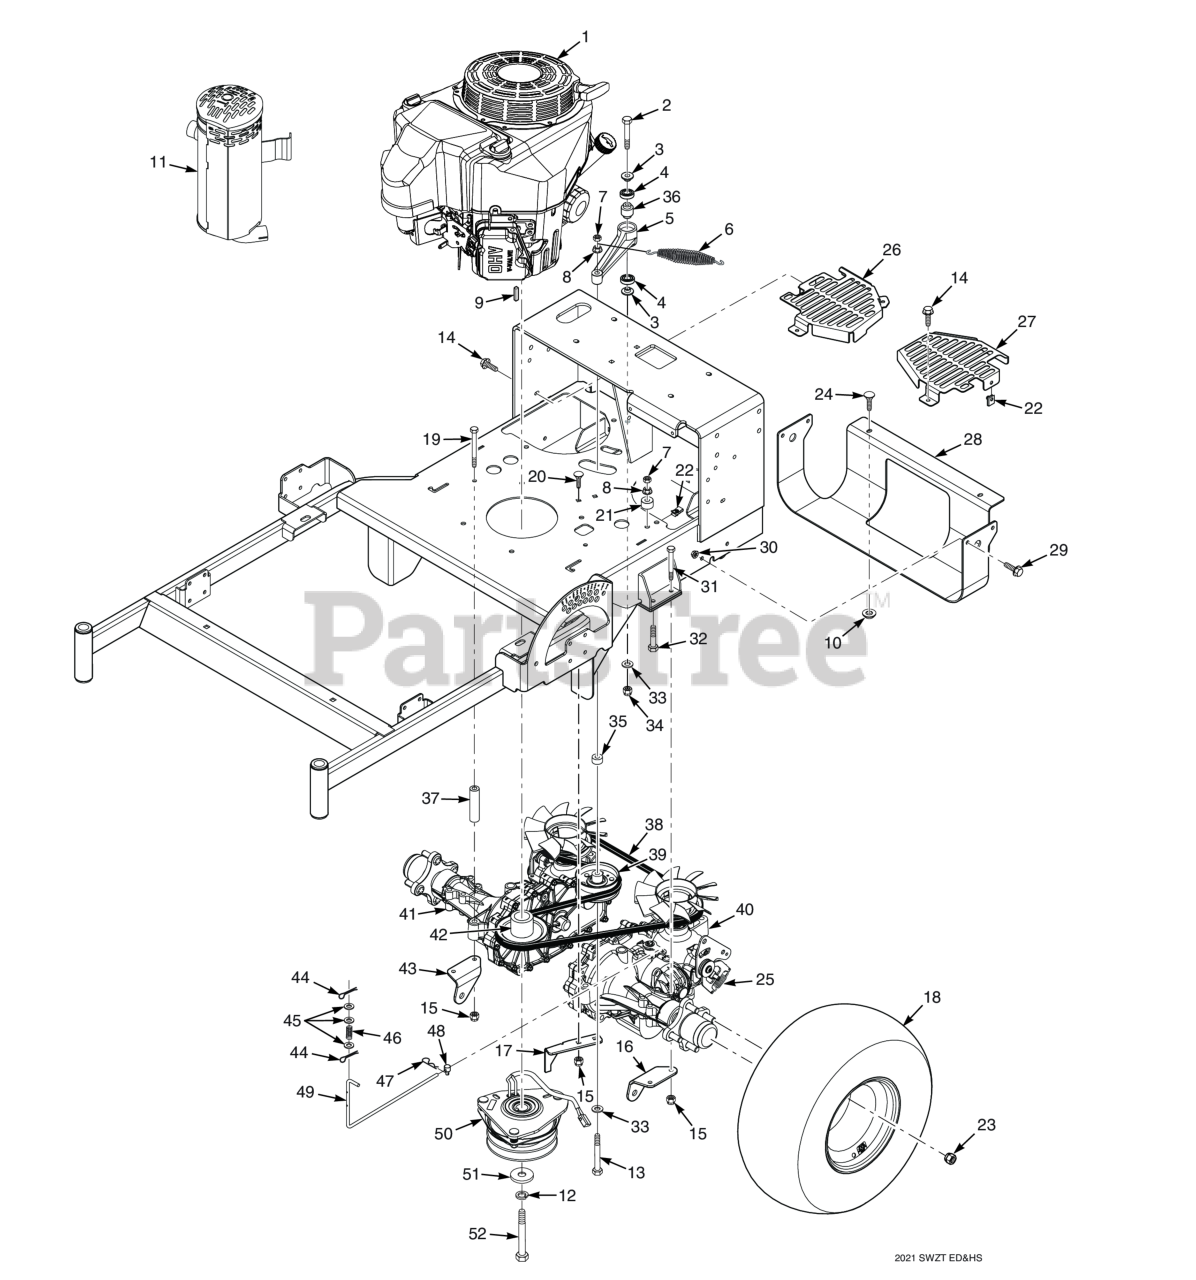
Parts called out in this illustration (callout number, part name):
1	Engine, Kawasaki 14FS (FS481V)
2	Bolt, Hex Head 3/8-16 x 3" - 52"
3	Spacer, Controls
4	BEARINGS, BALL, NEUTRAL RETURN
5	Trans. Idler Arm Assy. (Includes 24, 79)
6	Spring, Transmission Idler
7	Bolt, Hex Head 3/8-16 x 1" Ser. Flg.
8	NUT, 3/8-16 SERRATED FLANGE HEX HEAD
9	KEY, 1/4 X 1/4 X 2-1/2"
10	Nut, Push-On 5/16-18
11	Muffler, Kawasaki (FS651) - SWZT61
12	Lockwasher, 7/16� Spring
13	Capscrew, Hex Head 3/8-16 x 3-3/4"
14	Bolt, Serrated Flange Hex Head 1/4 x 20 x 3/4"
15	HEX NUT, ELASTIC STOP LOCK, 5/16-18
16	Pusharm Mount Bracket, LH
17	Bracket, Anti-Rotation
18	Wheel Assembly (#12 tire mounted to #13 rim)
19	Bolt, Hex Head 5/16-18 x 6-1/2"
20	Bolt, Carriage 5/16-18x1" (large frame units only)
21	SPACER, J PULL ROD
22	Bolt, Hex Head 3/8-16 x 1"
23	Wheel Nut, 1/2-20 x 13/16
24	Bolt, 5/16-18 x .75 RHSN Carriage
25	Spring, RTN
26	Fan Cover, RH
27	Fan Cover, LH
28	Skid Plate
29	Capscrew, 5/16-18 x .75 Serrated Flange Hex Head
30	Nut, Serrated Flange 5/16-18 (Right Front Engine Mounting, Briggs and Kohler Only)
31	Bolt, Hex Head 5/16-18 x 3.00"
32	Bolt, Hex Head 3/8-16 x 2-1/2" 1.5 Thread Grd.8
33	Flatwasher, 3/8 (.391 x .938 x .105 HD) Grade 8
34	HEX NUT, ELASTIC STOP LOCK, 3/8-16
35	Spacer, Idler Pulley - SFZ61
36	Spacer, Bearing
37	Spacer, Axle
38	Belt, Transmission Drive
39	Pulley, 3-1/2" Dia.
40	Transaxle Assy., (ZH-GMCC-SLUB-1MTX)
41	Transaxle Assy., (ZH-KMCC-3LUC-1MTX)
42	Pulley, 4-1/2" Dia. - 1" Bore
43	Pusharm Mount Bracket, RH
44	COTTER PIN, 3/32 X 1"
45	Flatwasher, 1/4" (.312 x .750 x .065")
46	Spring, Dump Valve Link
47	Pin, Rue Cotter 3/8" Diameter
48	Joint, Swivel
49	Link, Dump Valve
50	Electric Clutch Assembly
51	Flatwasher, 7/16-.469 x 1.75 x .25 (48, 52)
52	Bolt, Hex Head 7/16-20 x 3" w/t Patch
